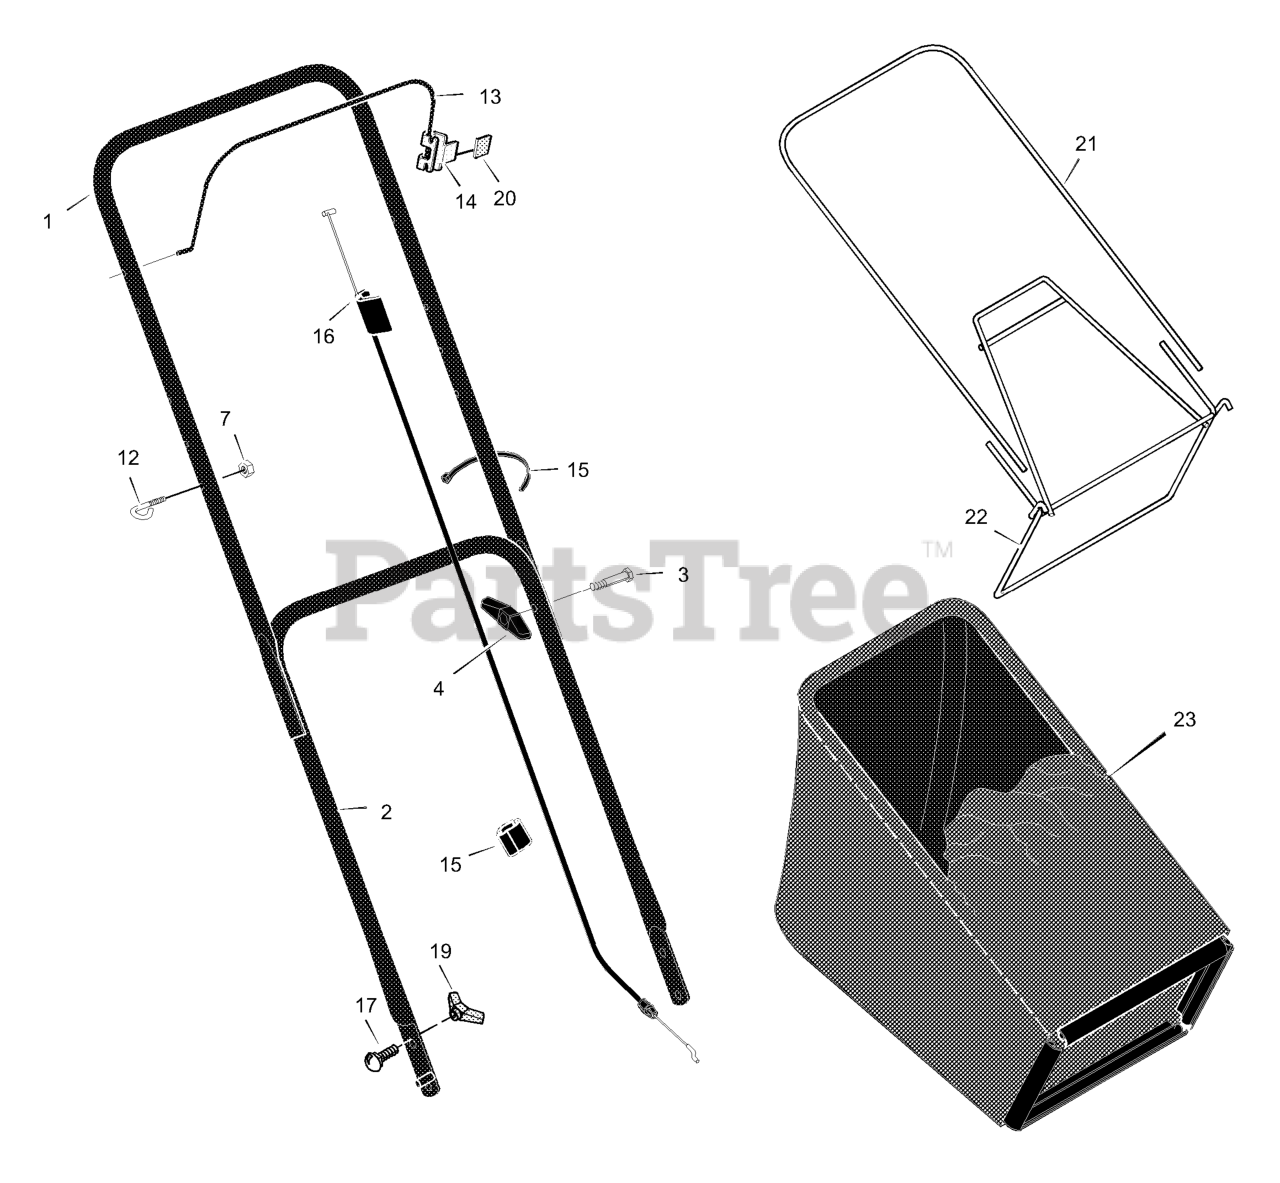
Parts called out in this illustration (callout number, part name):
1	Handle, Upper (Black)
2	Handle, Lower (Black)
4	Knob, Plastic
7	Locknut
12	Guide, Rope
13	Engine Stop Lever
14	Bracket, Stop Lever
15	Clip, Cable
16	Engine Stop Cable
17	Bolt, Carriage
19	Knob, Plastic
20	Grip, Vinyl
21	Frame, Top
22	Frame Assembly
23	Bag, Cloth
